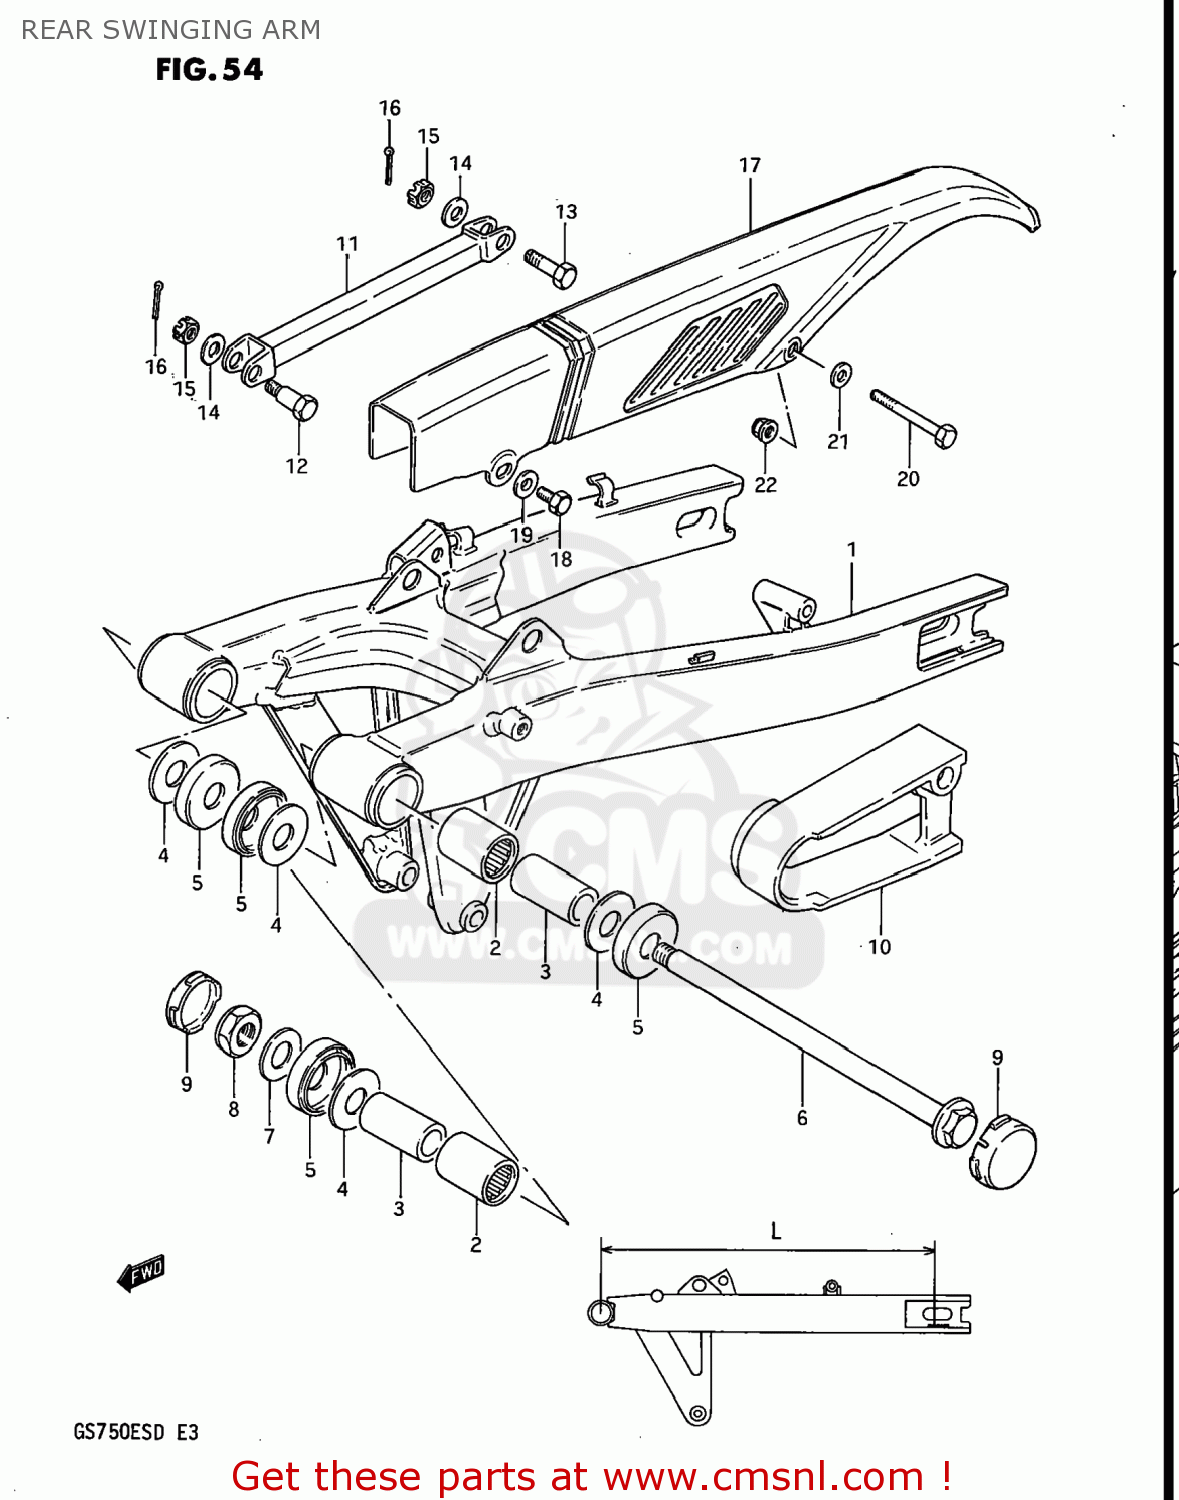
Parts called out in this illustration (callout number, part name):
1	SWING ARM ASSEMBLY,REAR
2	BEARING(25X33X30)
3	BUSHING
4	SPACER,RR SWGARM PIVOT
5	WASHER
6	COVER,RR SWINGINGARM PIVOT
7	SHAFT,REAR SWING ARM
8	WASHER
9	NUT
10	CAP,PIVOT
11	BUFFER,CHAIN TOUCH DEFLECTOR
12	TORQUE LINK,REAR
13	BOLT
14	BOLT(10X39)
15	WASHER
16	NUT
17	PIN 20X20
18	CASE,CHAIN
19	BOLT
20	WASHER
21	BOLT 6X60
22	WASHER (6.5X18X1.6)
23	NUT 6MM
